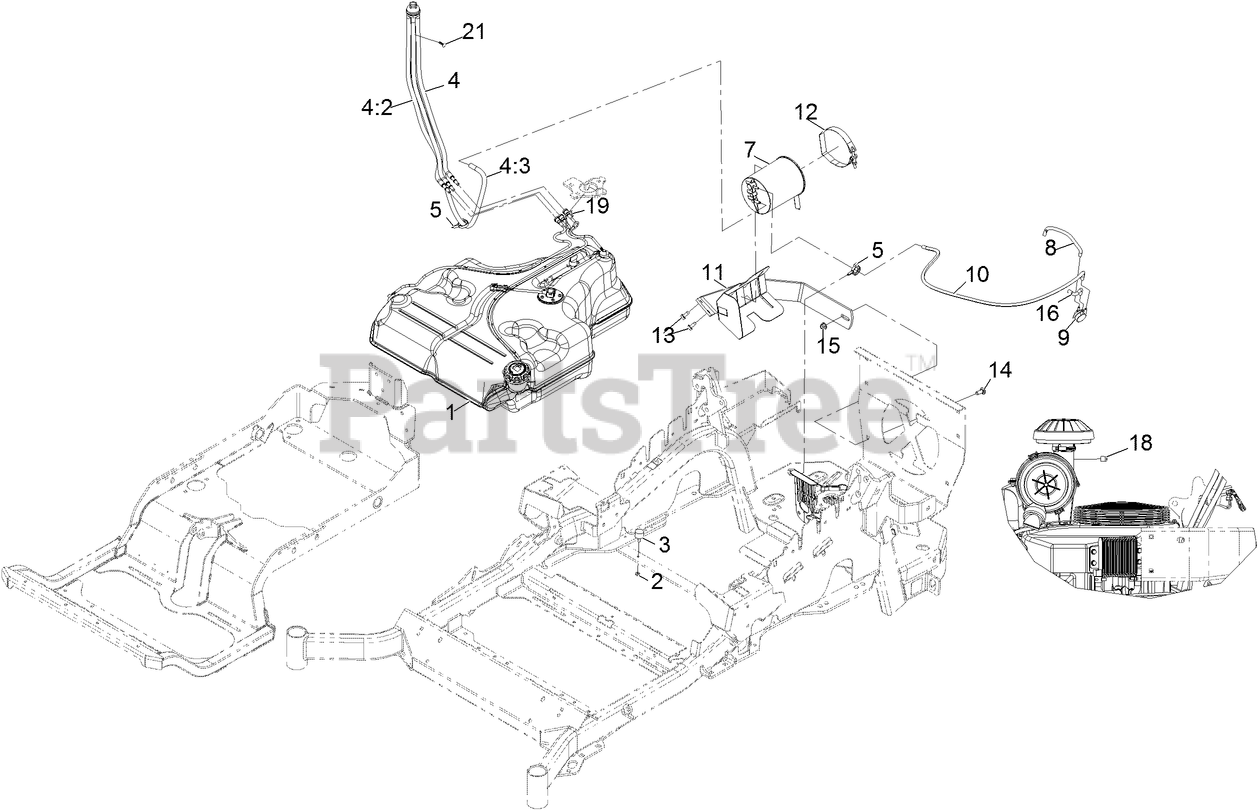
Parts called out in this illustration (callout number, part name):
1	FUEL TANK ASM
2	NUT-JAM
4	FUEL MANIFOLD VENT ASM
4:2	HOSE-FUEL
4:3	HOSE-FUEL
5	CLAMP-HOSE
7	CANISTER-CARBON, 1200CC
8	HOSE-VENT,FORMED
9	VALVE-CONTROL, VACUUM
10	HOSE,VENT,FORMED
11	MOUNT-CANISTER
12	CLAMP, T-BOLT
13	Screw-HWH 5/16-18 X 3/4 Tf
14	SCREW-CARR
15	NUT-HF, NI
16	HOSE-VENT, FORMED
18	PLUG-PORT
19	RETAINER-LINE, VAPOR
21	PLUG-PLASTIC
